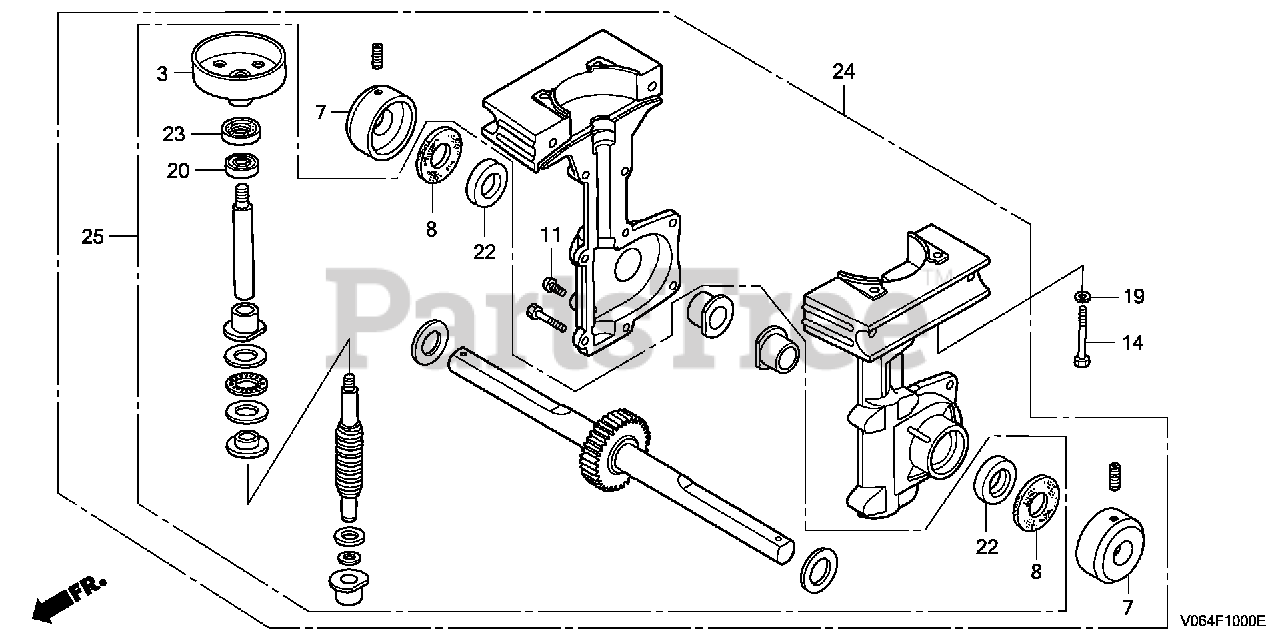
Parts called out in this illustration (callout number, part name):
3	CLUTCH (OUTER)
7	CAP, DUST PROTECTOR
8	SEAL, FELT
11	SCREW, PHILLIPS (1/4-20X1/2)
14	SCREW (1/4-20X2)
19	WASHER, LOCK
20	BEARING, ROLLER
24	TRANSMISSION ASSY. (N/A: ORDER #25, 06200-V06-305 , & ADDIT'L PARTS IN PIB10-01) (NA USE ALT:06200-V06-305)
25	TRANSMISSION KIT (SEE PIB #10-01)
